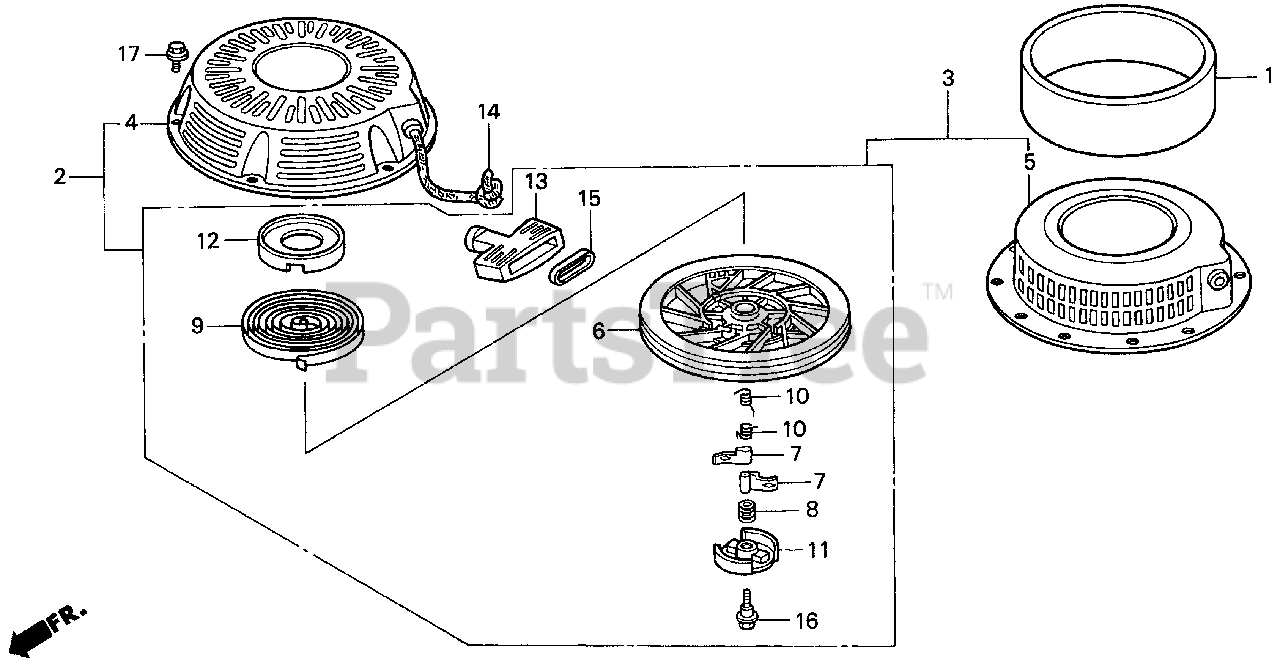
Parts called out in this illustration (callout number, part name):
1	FILTER, AIR
3	STARTER ASSY., RECOIL *R8* (BRIGHT RED)
3	STARTER ASSY., RECOIL *NH1* (BLACK)
5	CASE, RECOIL STARTER *R8* (BRIGHT RED)
5	CASE, RECOIL STARTER *NH1* (BLACK)
6	PULLEY, RECOIL STARTER
7	RATCHET, STARTER
8	SPRING, FRICTION
9	SPRING, STARTER RETURN
10	SPRING, RATCHET
11	RETAINER, SPRING
13	GRIP, STARTER
14	ROPE, RECOIL STARTER (NA USE ALT:08550-ZG921-11)
15	GRIP, REINFORCEMENT
16	SCREW, CENTER
17	BOLT, FLANGE (6X10)
